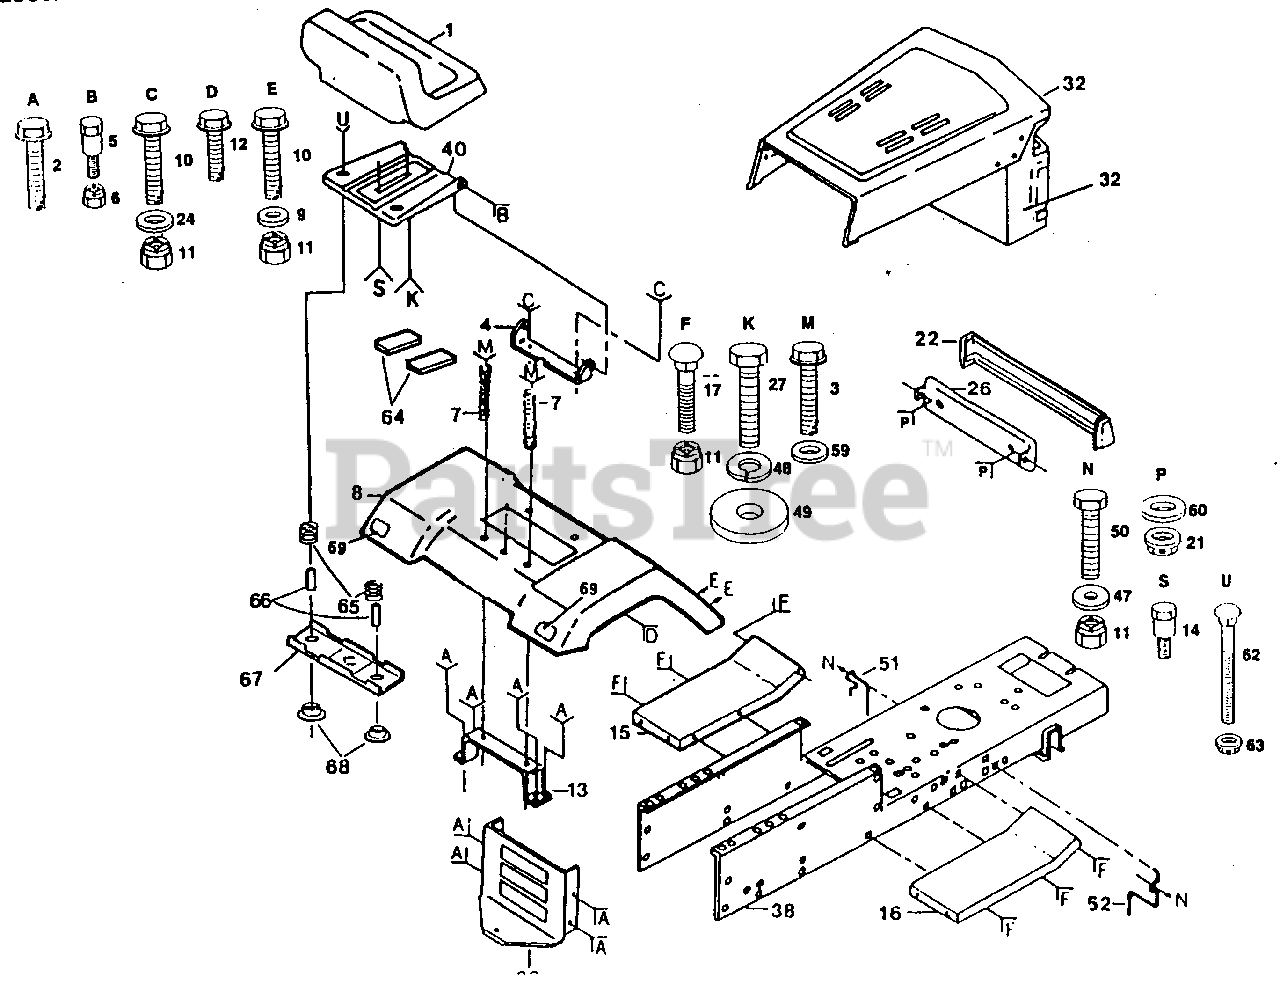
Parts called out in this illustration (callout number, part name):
1	Seat (AYP part number)
2	Screw, Hex, Washer Thread Rolling 3/8 - 16 x 3/4 Type TT
3	Screw, Hex, Washer Thread Rolling 3/8 -16 x 1
4	Bracket, Plvot, Seat (AYP part number)
5	Bolt, Shoulder 5/16 - 18 (AYP part number)
6	Nut, Crownlock 5/16 - 18
7	Spring, Seat
9	Washer 13/32 x 13/16 x 12 Ga.
10	Bolt, Hex, Washer Thread Rolling 3/8 (AYP part number)
11	Nut, Crownlock 3/8 - 16
12	Screw, Hex, Washer Thread Rolling 3/8 - 16 x 12
13	Bracket, Fender (AYP part number)
14	Bolt, Shoulder
15	Footrest, L.H.
16	Footrest, R.H.
17	Bolt, Carriage 3/8 - 16 x 3/4
21	Pal Nut 1/4 - 20
22	Lens (AYP part number)
24	Washer 13/32 x 3/4 x 10 Ga.
26	Bezel (AYP part number)
27	Bolt, Hex 1/2 - 13 x 7/8 Gr. 5 (AYP part number)
32	Hood and Grill Assembly
38	Chassls Assembly
39	Drawbar
40	Pan, Seat (AYP part number)
47	Washer 13/32 x 1-1/4 x 12 Ga.
48	Washer, Lock 1/2
49	Washer 17/32 x 1-3/16 x 12 Ga.
50	Bolt, Hex 3/8 - 16 x 1
51	Gulde, Belt, Lower, Englne Pulley, L.H.
52	Gulde, Belt, Lower, Englne Pulley, R.H.
59	Washer 13/32 x 1 x 14 Ga. (AYP part number)
60	Washer 9/32 x 3/4 x 16 Ga.
62	Bolt, Carriage 1/4 - 20 x 1-1/4
63	Nut, Hex Flange 1/4 - 20 (AYP part number)
64	Strip, Foam
65	Spring, Compression
66	Spacer, Split
67	Bracket, Switch Mount
68	Bushing, Snap
69	Reflector, Tail
